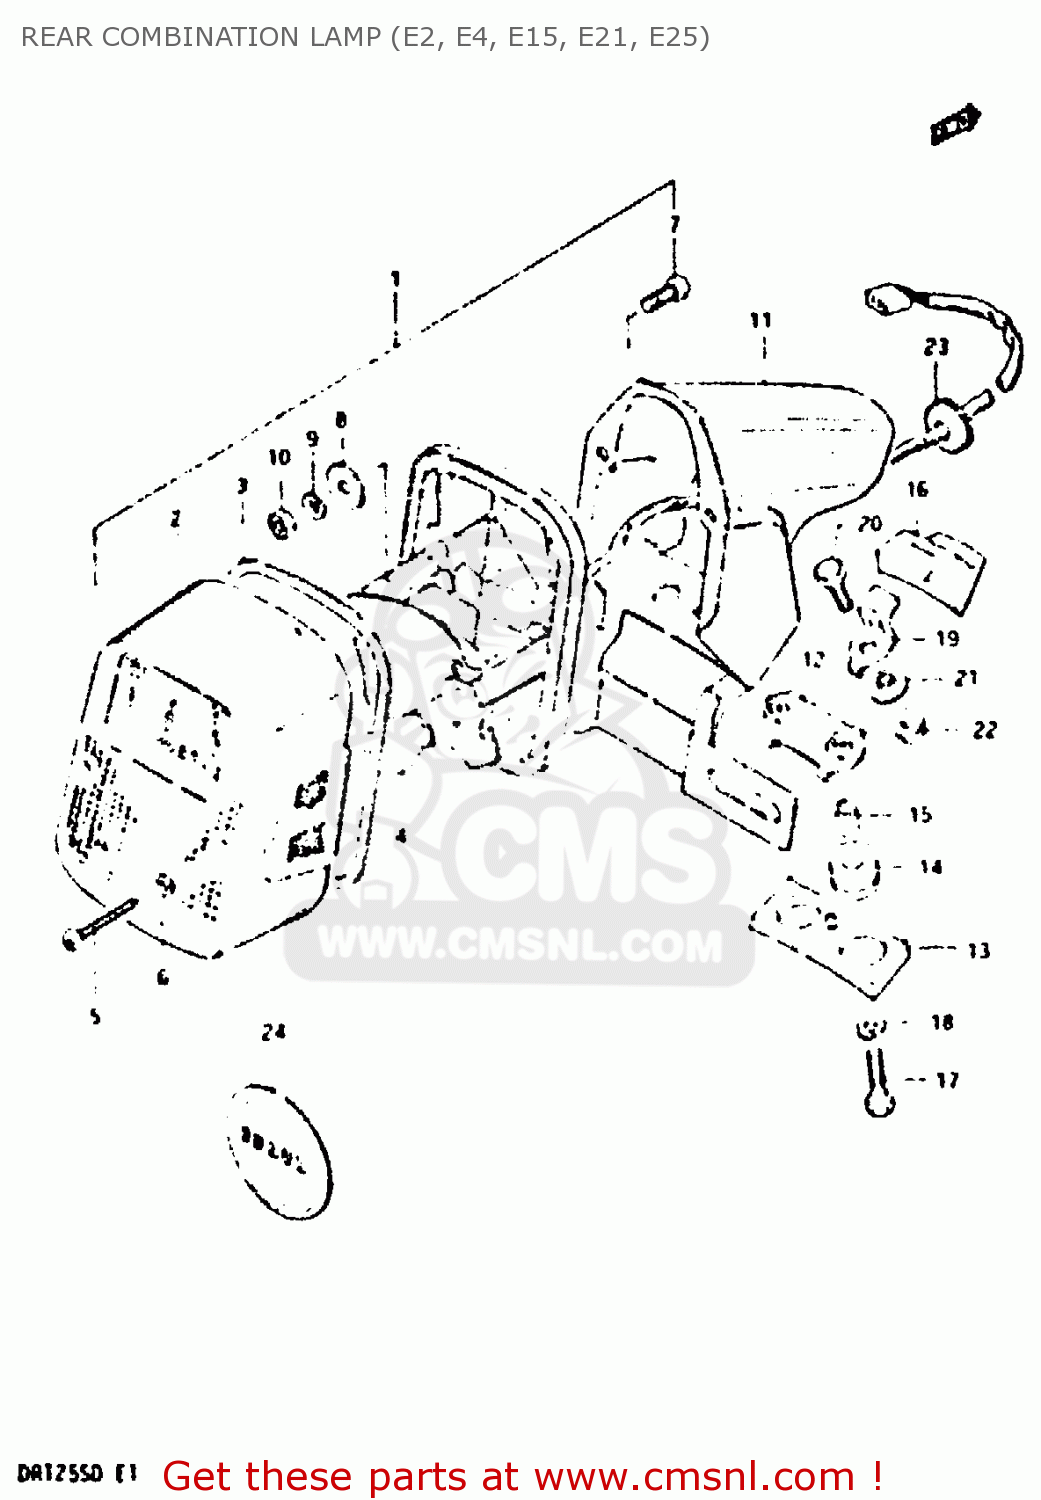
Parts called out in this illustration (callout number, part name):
1	LAMP UNIT, REAR COMBINATION
2	LENS,RR COMBI
3	GASKET (NAS)
4	BULB 12V21/5W
5	SCREW TAPP.
6	GASKET (NAS)
7	SCREW
8	WASHER,REAR COMBINATION LAMP
9	LOCK WASHER
10	NUT
11	BRACKET UNIT,TAIL LAMP
12	PLATE
13	CUSHION
14	CUSHION
15	SPACER
16	CUSHION,REAR COMBINATION LAMP
17	BOLT
18	LOCK WASHER
19	PLATE,RR COMBINATION LAMP
20	BOLT, UPPER
21	WASHER,LOCK
22	NUT
23	GROMMET
24	EMBLEM, REAR
